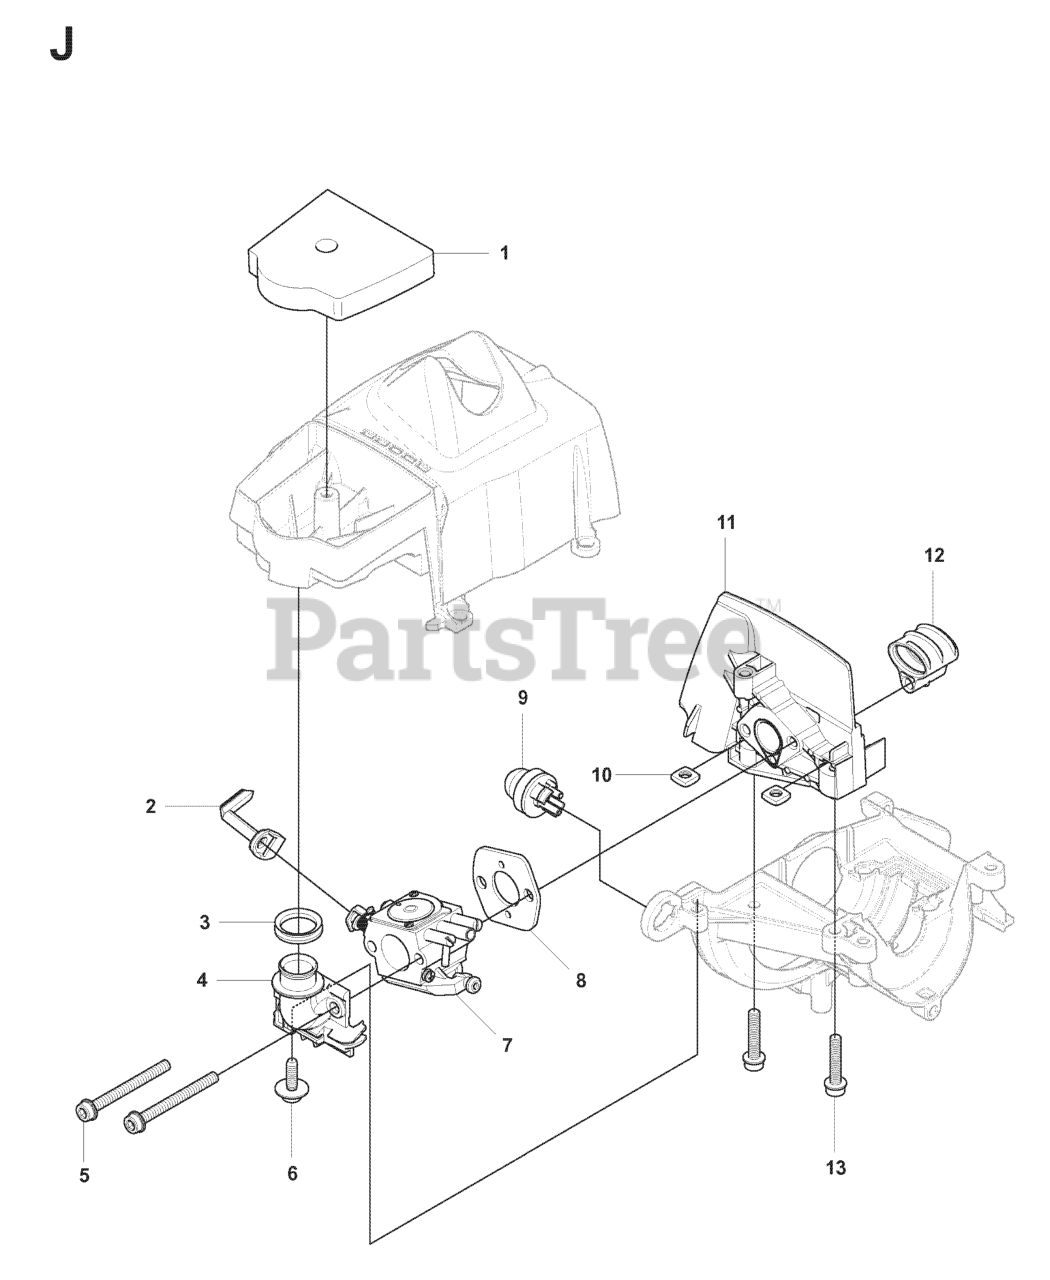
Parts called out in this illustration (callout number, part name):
1	AIR FILTER
2	CHOKE CONTROL
7	CARBURETOR
9	AIR PURGE BUBBLE
